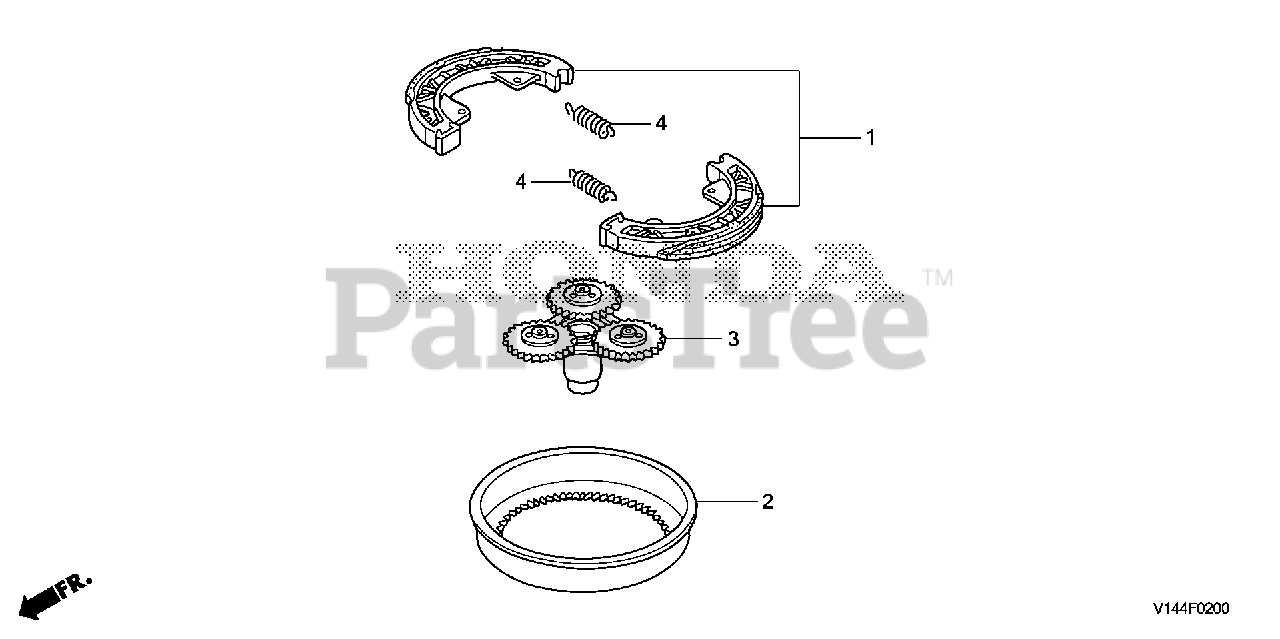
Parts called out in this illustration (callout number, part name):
1	SHOE SET, CLUTCH
2	CLUTCH OUTER
3	PLATE, DRIVE
4	SPRING, FR. BRAKE SHOE
